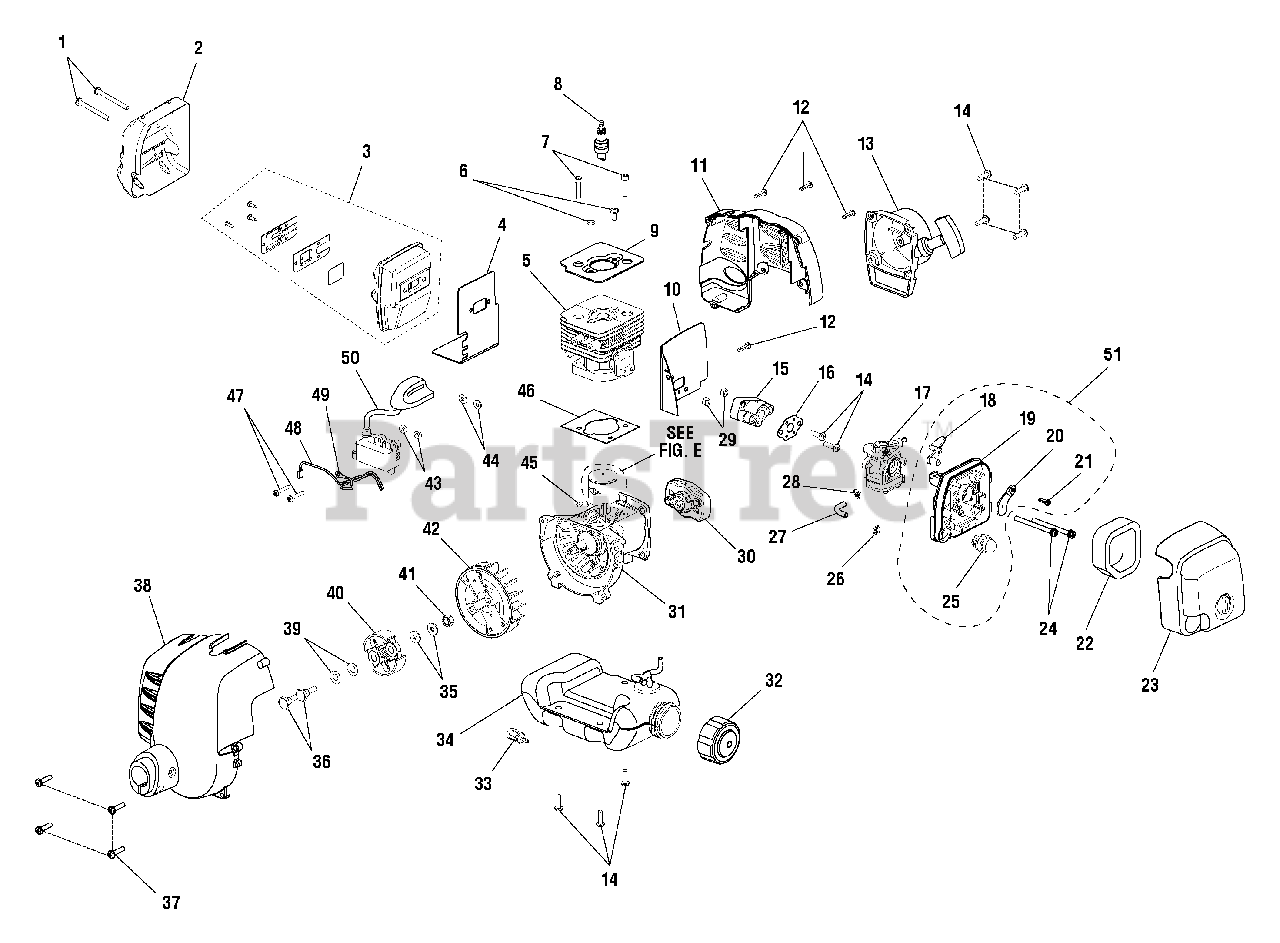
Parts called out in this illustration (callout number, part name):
1	SCREW (M5 X 50 mm TORX SLOTTED RECESSED PAN HD.)
2	HEAT SHIELD
3	MUFFLER ASSEMBLY .
4	MUFFLER GASKET
5	CYLINDER .
6	SCREW (M5 X 10 in. TORX RECESSED PAN HD.)
7	SCREW (M5 X 22 mm SOCKET HD.)
8	SPARK PLUG
9	CYLINDER PLATE
10	INSULATOR GASKET
11	ENGINE HOUSING, REAR .
12	SCREW (M4 X 16 mm TORX RECESSED PAN HD.)
13	STARTER RECOIL ASSEMBLY
14	SCREW (M5 X 16 mm Torx SLOTTED RECESSED PAN HD.)
15	HEAT DAM INSULATOR
16	CARBURETOR GASKET
17	CARBURETOR ASSEMBLY .
18	CHOKE LEVER .
19	CARBURETOR PLATE .
20	CHOKE PLATE .
21	SCREW (M4 X 12 mm SLOTTED RECESSED PAN HD.)
23	COVER ASSEMBLY .
24	SCREW (M5 X 60 mm, SLOTTED RECESSED PAN HD. MACHINE)
25	PRIMER ASSEMBLY
26	HOSE CLIP
27	FUEL LINE
28	HOSE CLIP
29	NUT (M5 x .8 mm)
30	PULLEY ASSEMBLY
31	CRANKCASE ASSEMBLY
32	FUEL CAP ASSEMBLY
33	FUEL FILTER
34	FUEL TANK ASSEMBLY
36	CLUTCH SCREW
37	SCREW (M5 X 20 mm TORX SLOTTED RECESSED PAN HD.)
38	FRONT HOUSING ASSEMBLY
39	CURVED WASHER
40	CLUTCH ASSEMBLY
41	ROTOR NUT
43	IGNITION COIL SPACER
44	WASHER (3/16 x 3/64) .
45	WOODRUFF KEY (10 mm X 3 mm) .
46	GASKET .
47	SCREW (M4 X 22 mm TORX SLOTTED RECESSED PAN HD.)
48	LEAD ASSEMBLY, BLACK .
49	LEAD ASSEMBLY, RED
50	COIL BOOT ASSEMBLY
51	FILTER HOUSING ASSEMBLY
